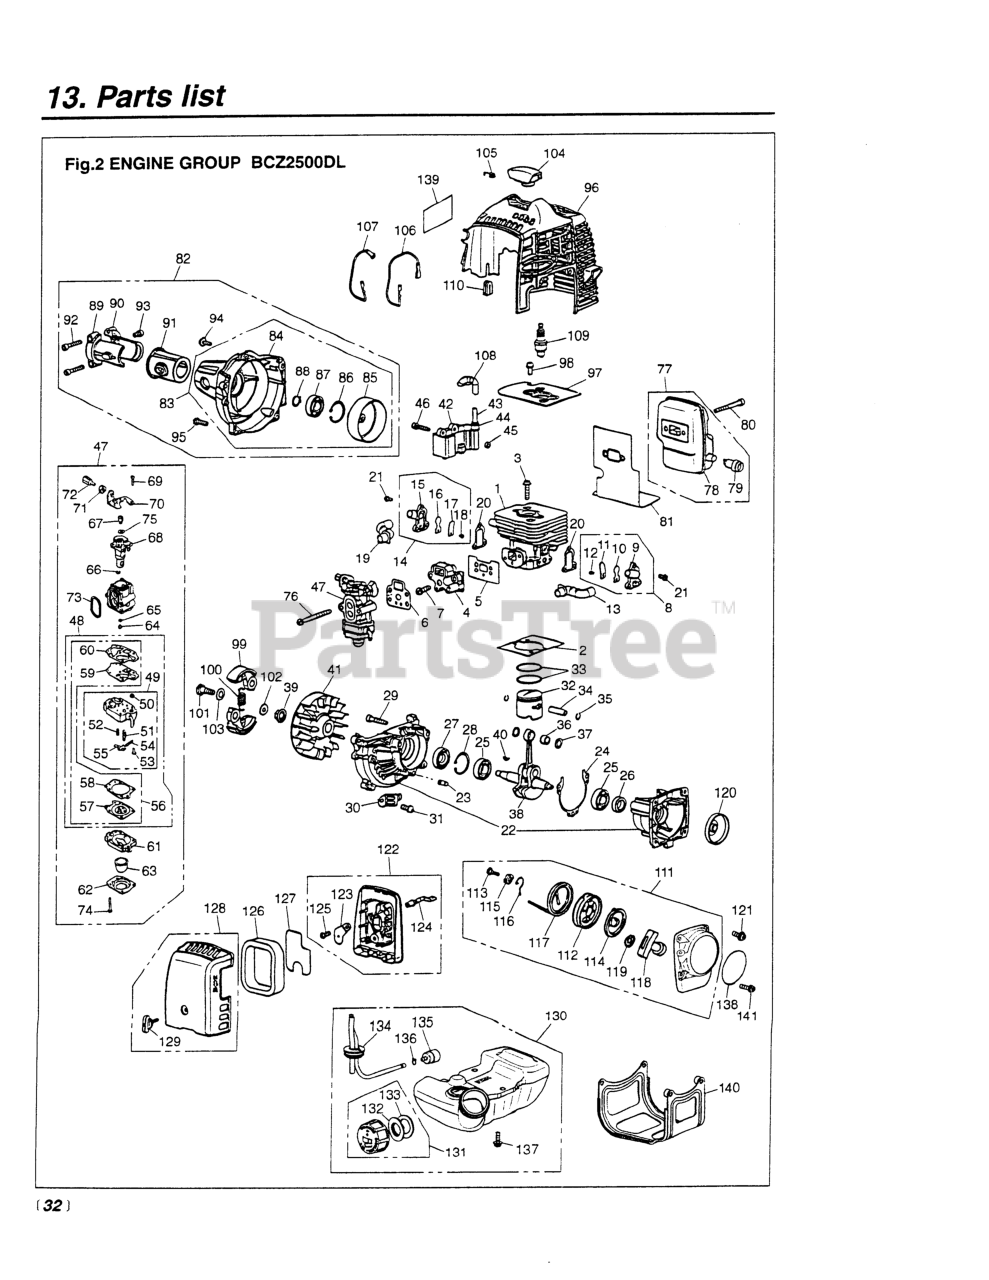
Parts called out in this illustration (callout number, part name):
2	GASKET, BASE
3	BOLT, M5 X 22
4	INSULATOR (USE -13161)
5	GASKET, INSULATOR
6	GASKET, CARBURETOR
9	CASE VALVE
10	VALVE, REED
11	STOPPER
12	SCREW, M3 x 8
13	PIPE, AIR
16	VALVE, REED
17	STOPPER
18	SCREW, M3 x 8
19	PIPE, AIR (F)
20	GASKET, VALVE
22	CRANKCASE COMP (USE 4810-21101
23	PIN
24	GASKET
25	BEARING
26	SEAL
27	SEAL, OIL (RPLS 1140-21220)
28	RING, SNAP, M28 x 1.2
29	BOLT, M5 X 30
32	PISTON
33	RING, PISTON
34	PIN, PISTON
35	RING, SNAP (RPLS 1101-41320)
37	WASHER
38	CRANKSHAFT COMPLETE
40	KEY
41	ROTOR
42	COIL-A
43	CORD
44	CAP
45	SPACER (RPLS -71260)
46	BOLT, M4 x 22
49	BODY ASSY KIT
50	SCREEN
51	VALVE, INLET
53	SCREW
54	PIN
55	LEVER
57	DIAPHRAGM
58	GASKET, DIAPHRAGM
59	DIAPHRAGM, PUMP
60	GASKET, PUMP
61	BODY, PURGE
62	COVER, PUMP
63	PUMP, PRIMING
64	JET (USE -81251)
65	RING, O
66	RING
67	SWIVEL
68	VALVE ASSY
69	SCREW
71	NUT, CABLE ADJUSTER
72	SCREW, CABLE ADJUSTER
73	RING
74	SCREW
75	WASHER
77	MUFFLER ASSEMBLY
78	MUFFLER (USE -15111)
79	ARRESTER
80	BOLT, M5 x 50
81	GASKET (USE 4810-15410)
84	COVER, FAN (USE -31111)
86	RING, SNAP, M28 x 1.2
87	BEARING
88	RING, SNAP (RPLS 3130-13270)
91	CUSHION
92	BOLT, M5 X 30
93	BOLT (USE 3310-31720)
94	SCREW
97	PLATE
99	SHOE (RPLS 1100-51114)
100	SPRING
101	BOLT
102	WASHER, FLAT (USE 182303)
105	SPRING
106	CORD (BLACK)
107	CORD, EARTH (RED)
110	GROMMET
111	RECOIL ASSEMBLY
112	REEL
113	SCREW
114	SPRING, SPIRAL
115	COLLAR
116	ARM
117	ROPE (USE 4810-75160)
118	KNOB (RPLS -75420)
119	PLATE, STOPPER
120	PULLEY
121	SCREW
122	BODY ASSEMBLY
123	PLATE, CHOKE
124	LEVER, CHOKE
125	SCREW (REPLACES 50030272)
126	ELEMENT
127	SCREEN
128	COVER ASSEMBLY
129	KNOB (RPLS -82220)
130	TANK ASSY (USE -87001)
132	HOLDER (REPLACES -85230)
133	PACKING
134	PIPE COMPLETE
135	FILTER (RPLS 1850-85300)
136	CLIP (REPLACES 2841-31280)
137	SCREW
138	LABEL, RECOIL
139	LABEL, COVER (RPLS -31130)
